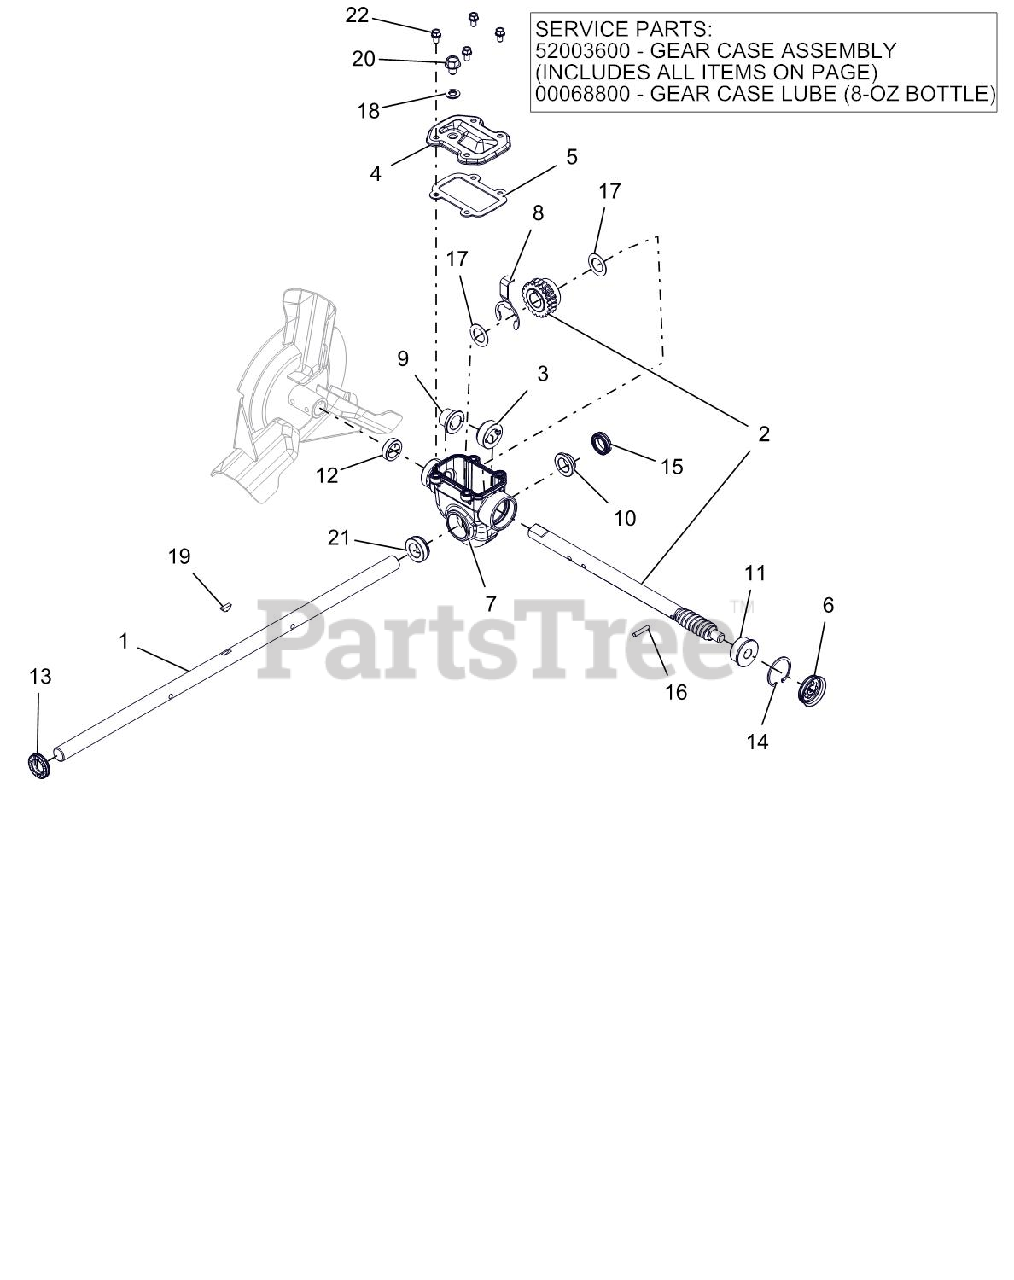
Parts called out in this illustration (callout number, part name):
1	SHAFT, RAKE - 24" (.750 DIA)
2	SHAFT AND WORM GEAR ASSEMBLY
3	THRUST COLLAR, .75" ID SLIPFIT
4	COVER, TOP - COMPACT
5	GASKET, TOP - COMPACT GEARCASE
6	COVER, GEAR CASE 1.50"
7	GEARCASE, COMPACT ALUMINUM
8	BUSHING RETAINER, COMPACT
9	BSHG-FLG .755X.878X.75X1.25
10	BSHG-FLG .755X.878X.424X1.25
11	BSHG-FLG .503X1.303X.62X1.465
12	SEAL-OIL .748X1.125X.312 TB2-H
13	SEAL-OIL .748X1.300X.250 TBC29
14	RG-RTNG-INT 1.500X.050
15	SEAL-OIL .748X1.125X.312 TBC29
16	PIN-STR .188X1.00 6150
17	WSHR-FL-STL .760X1.225X.032 YZ
18	WSHR-BND-SEAL .38X.75X.11 GALV
19	KEY-WDRF .19X.63 HRD #61
20	@SCR-ROLOK .38-16X.50 HWH YWZC
21	BSHG-FLG COMPACT, RIGHT
22	BOLT, SEMS .25-20X.50 GR5 YWZC
23	GEAR CASE, 24" ALUM SM TOP-LD
24	ARIENS L3 LUBE, 8 OZ BOTTLE
